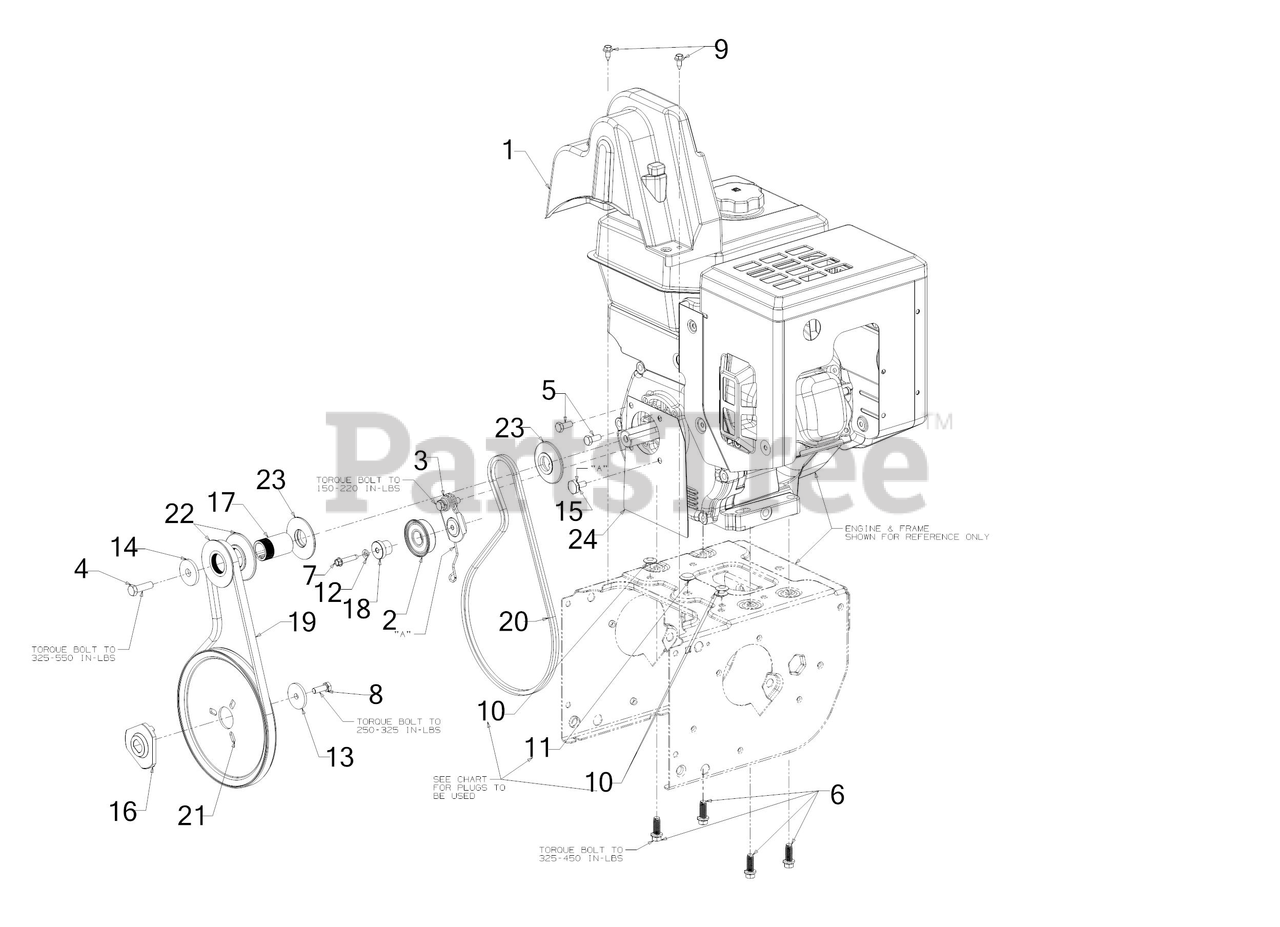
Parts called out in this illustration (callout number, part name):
1	BELT COVER (LARGE BLOCK)
2	IDLER PULLEY ASSEMBLY
3	IDLER ASSEMBLY
4	SCREW 3/8-24X1.25
5	SCREW 5/16-24 x .750 GR5
6	SCREW 3/8-16 x 1
7	SCREW 1/4-20 x 1.25
8	SCREW 5/16-24 x .875 GR5
9	SCREW 1/4-20X.625
10	PLUG-3/8 DIA ID x 3/32
11	PLUG-1/2 ID x 3/32
12	LOCK WASHER
13	FLAT WASHER
14	FLAT WASHER .45 x 1.5 x .172 HT
15	SHOULDER SCREW
16	ADAPTER PULLEY .75 DIA W/DD
17	PULLEY SPACER
18	SHOULDER SPACER
19	BELT-.500 x 37
20	BELT-3L x 36.64
21	AUGER PULLEY
22	HALF PULLEY 4L V x 2.6 OD
23	HALF PULLEY 3/8-V x 2.2
24	ENGINE PLATE (FRONT COVER)
